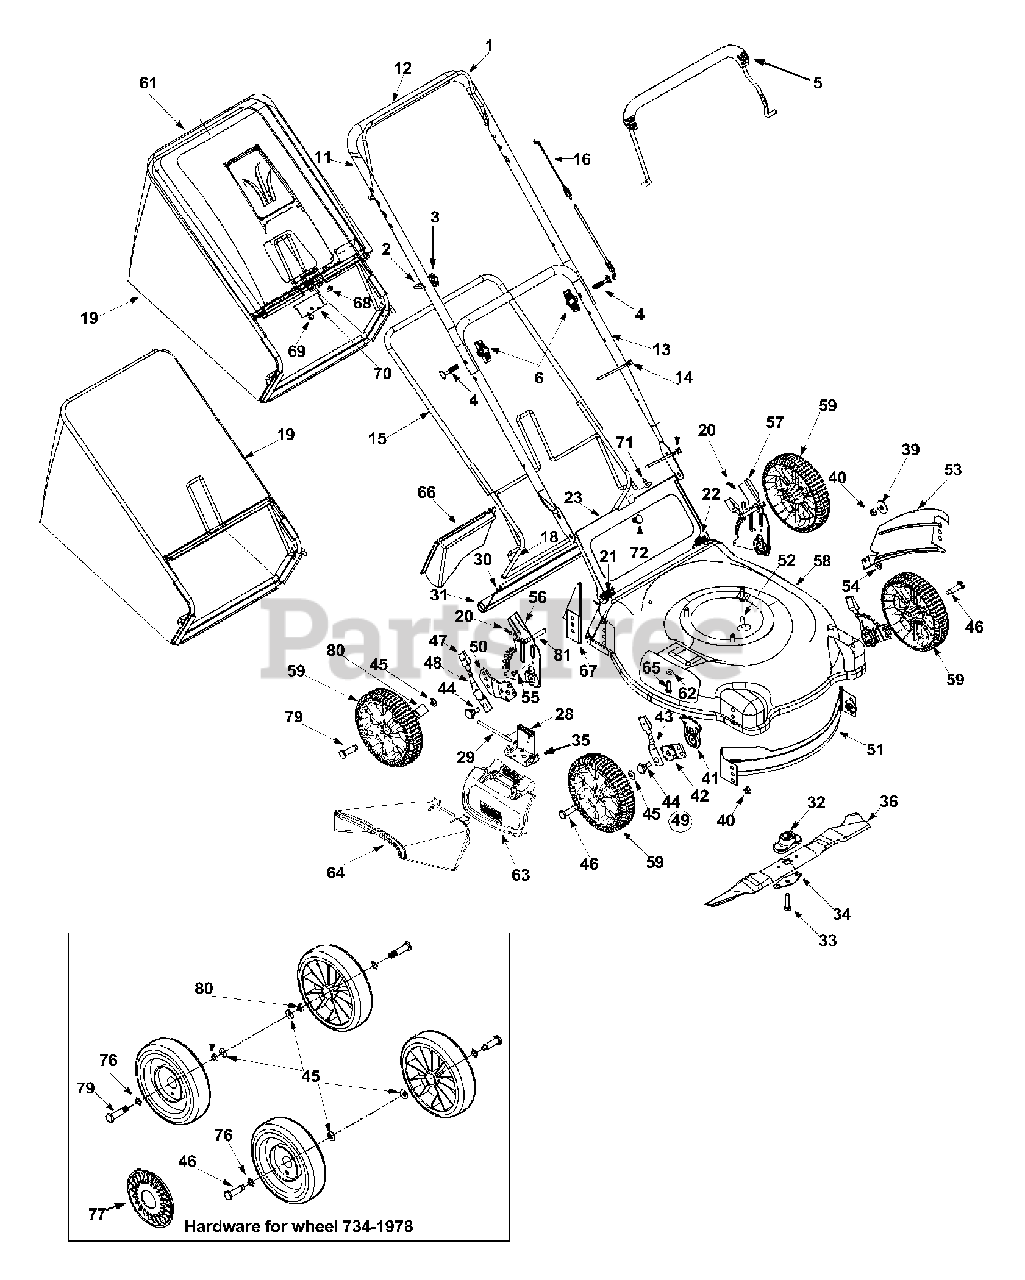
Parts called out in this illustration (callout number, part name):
2	Rope Guide
3	Handle Knob 1/4-20 Thd.
4	Curved Hd. Bolt 5/16-18 x 2"
5	Bail Cover
6	Hand Knob
12	Foam Grip
14	Cable Tie
16	Control Cable - 40"
20	Int. Cotter Pin 5/16" Dia.
21	Door Spring - R.H.
22	Door Spring - L.H.
29	Hinge Pin
30	Wire Rod
31	Rear Flap
32	Blade Adapter
33	Hex Bolt 3/8-24 x 1.5" Lg.
34	Blade Bell Support
36	21" Mulching Blade
40	Flange Nut 3/8-16 Thd.
41	Height Adj. Plate
43	Front Spring Lever Ass'y. w/Knob
44	Shld. Bolt .5" Dia. x .357"
45	Bell Washer .38" I.D. x .88" O.D.
46	Front Axle Bolt
47	Spring Lever Knob
48	Rear Spring Lever
49	Height Adj. Assy. Comp. - RH
50	Pivot Bar R.H.
54	Torx Mach AB-Tap Scr. 1/4 x.62"
55	Hex Ind Wash. Scr. 1/4-14:.625
56	Handle Brkt. Ass'y.-RH
57	Handle Brkt. Ass'y.-LH
61	Hard Top Cover w/ Icon
62	Bell Washer 1/4" I.D.
63	Hinged Mulching Plug
64	Chute Deflector: Side Discharge
65	Hex Hd Self-Tp Scr. 1/4-20 x .5"
66	Mulching Baffle Plug
68	Pan Hd. Mach. Scr. 1/4-20:.5" Lg.
69	Hx. Nylon L-Nut - 1/4-20 Thread
71	Truss Scr. #10-24 x .38" Lg.
76	Wave Washer
77	Hub Cap - Rad. Spoke - Grey
79	Rear Axle Bolt
80	Spacer
81	Weld Pin
